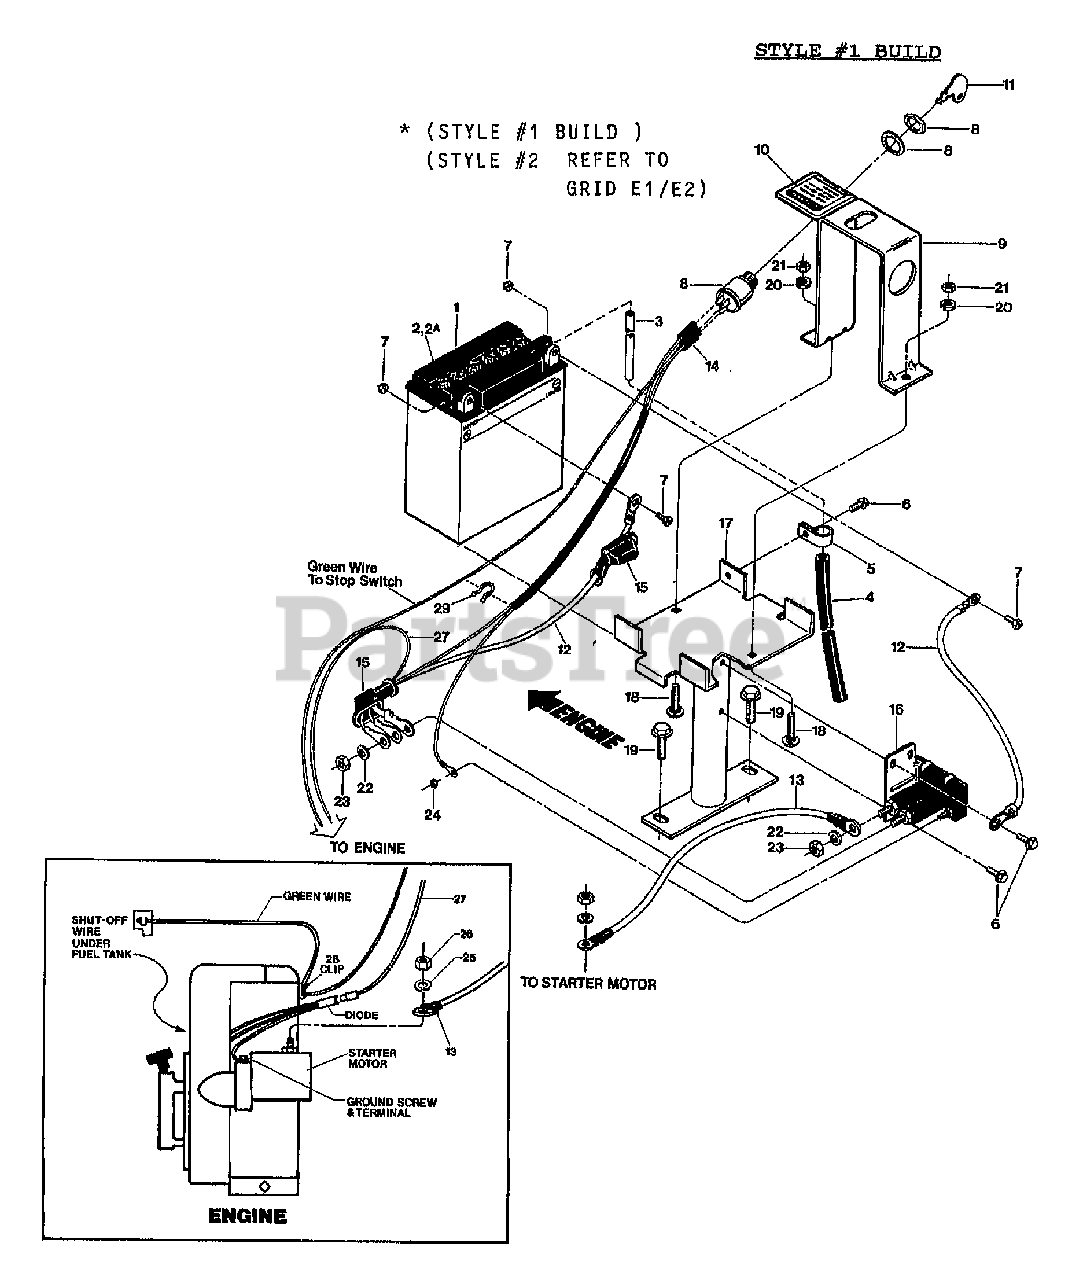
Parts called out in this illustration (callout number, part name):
1	BATTERY
2	CAP-YELLOW
2A	CAP-BATTERY WHITE (PONY)
3	TUBE-VENT BATTERY/HSE
4	TUBING-RUBBER
5	CLAMP
6	SCR-HWH 1/4-20 X .5 STH
7	HDW PKG-BATTERY TERMINAL
8	ASSM-KEYSWITCH W/DECAL
9	KEY PLATE/CLAMP PNT
10	DECAL-KEYSWITCH
11	KEYS(1 PAIR) FOR SWITCH
12	CABLE-BATTERY-12"
13	CABLE-BATTERY 12"
14	ASSM-HARNESS 2647/20857 (AVAILABLE AS COMPLETE ASSEMBLY ONLY)
15	BOOT-BATTERY CABLE
16	SOLENOID
17	BRKT-BATTERY OPC PNT
18	SCR-CARR 1/4-20X1.25
19	SCR-HFLK 5/16-18X1.00 ZP
20	WASHER-LK .25 ZP
21	NUT-HEX 1/4-20 ZP
21	NUT-HF/LK 1/4-20 ZP
22	WASHER-LK .312 ZP
23	NUT-HEX 5/16-24
24	NUT W/LKWASHER #10-32 ZP
25	LOCKWASHER
26	NUT
27	WIRE-RECHARGE 5&7 BRIGGS
28	CLIP-SPECIAL
29	TIE-TWIST LOCK
